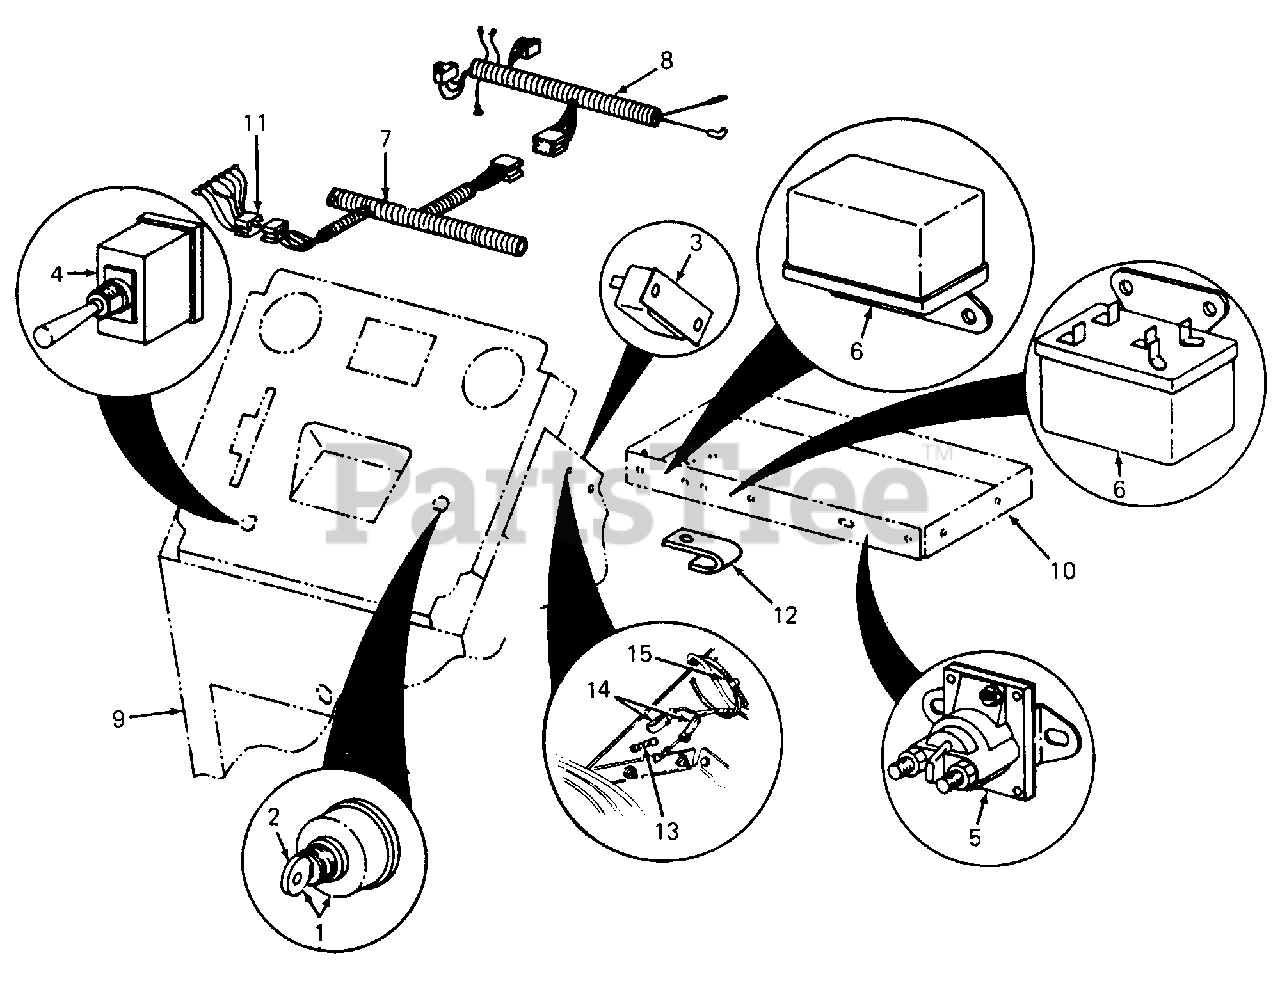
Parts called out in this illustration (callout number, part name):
1	Switch, Key
2	Key, Ignition (Set of 2)
3	Breaker, Circuit
4	Switch, PTO
5	Switch, Solenoid
6	Relay
7	Harness, Battery Tray
8	Harness, Main Wiring
10	Tray, Battery
11	Harness, Indicator
12	Clip, Cable
13	Fuse
14	Fuse Holder
15	Cable Tie
